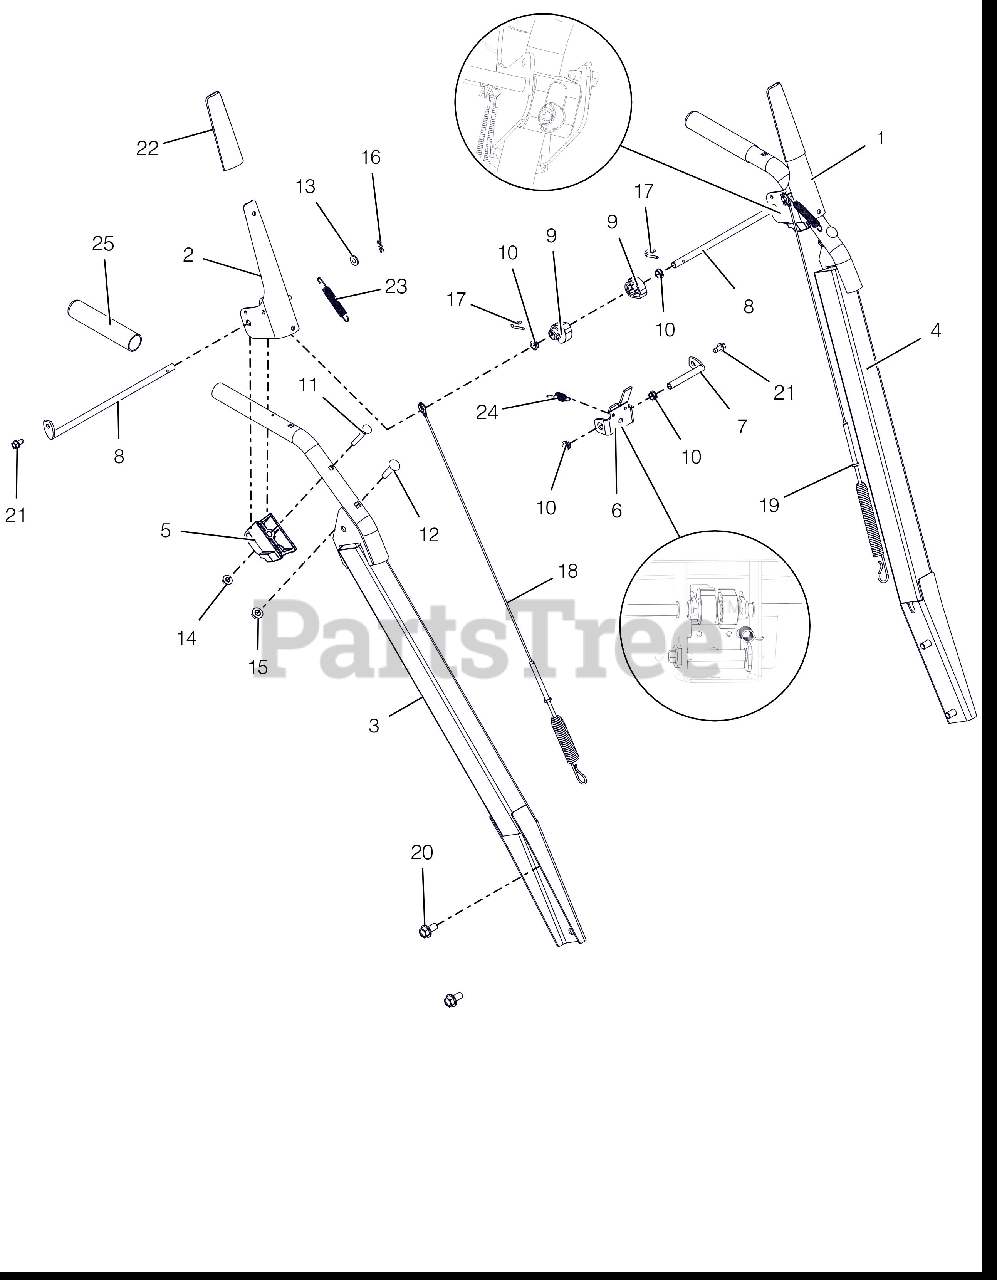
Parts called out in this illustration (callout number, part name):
1	LEVER, CLUTCH-LH
2	LEVER, CLUTCH-RH
3	HANDLEBAR, HEAVYDUTY-PRO-RH
4	HANDLEBAR, HEAVYDUTY-PRO LH
5	BLOCK, CLUTCH PADDLE
6	BRACKET, INTERLOCK ARM
7	ROD, PIVOT - INTERLOCK
8	ROD, PADDLE MOUNT - PRO
9	CAM, INTERLOCK
10	BUSHING, POLYLINER-.38 SNAPIN
11	BLT-RDHDXLSQNK .25-20X2.0 G5YZ
12	@BLT-RDHDSQNK .31-18X1.50 G5YZ
13	@WSHR-FL-STL.281X.62X.065 YWZC
14	@NUT-LK-CTR-FLG .25-20 YWZC
15	@NUT-LK-TOP-FLG .31-18 YWZC
16	PIN-HAIR INT .06X.18X.77
17	PIN, SPRING CLIP
18	CABLE, AUGER (DELUXE & PRO)
19	CABLE, UPPER TRACTION
20	BLT-SERHFWH .38-16X.75 YWZC
21	SCR-TAP .25-20X.50 HWH TR YWZ
22	SLEEVE, CLUTCH PADDLE-GRAY
23	SPRING, EXTENSION
24	SPRING-EXT .047X.438X1.45
25	GRIP,HANDLE-GRAY
